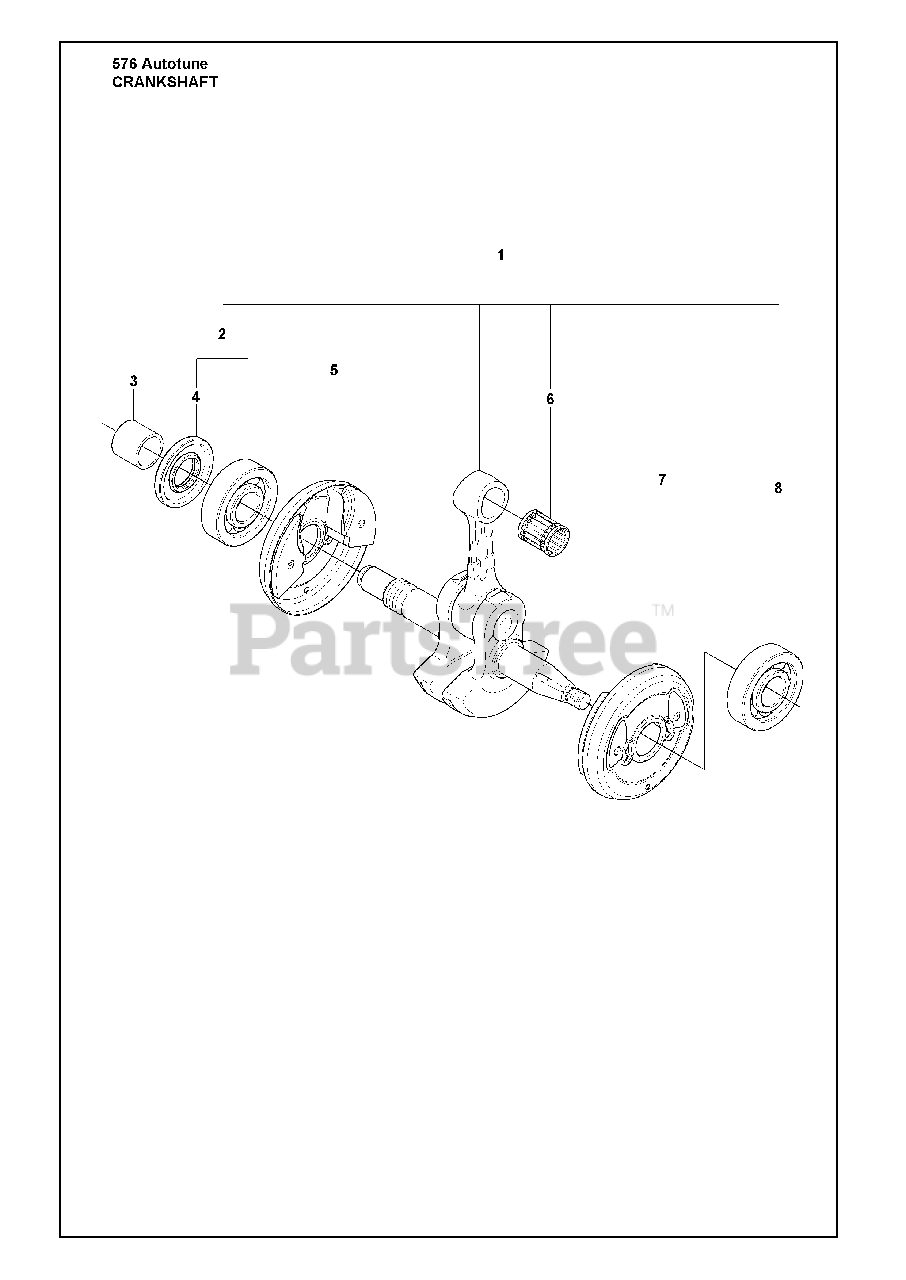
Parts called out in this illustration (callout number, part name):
1	RP CRANKSHAFT ASSY
2	%BALL BEARING
4	RADIAL SEAL
6	SUPPORT BUSHING
8	BALL BEARING
